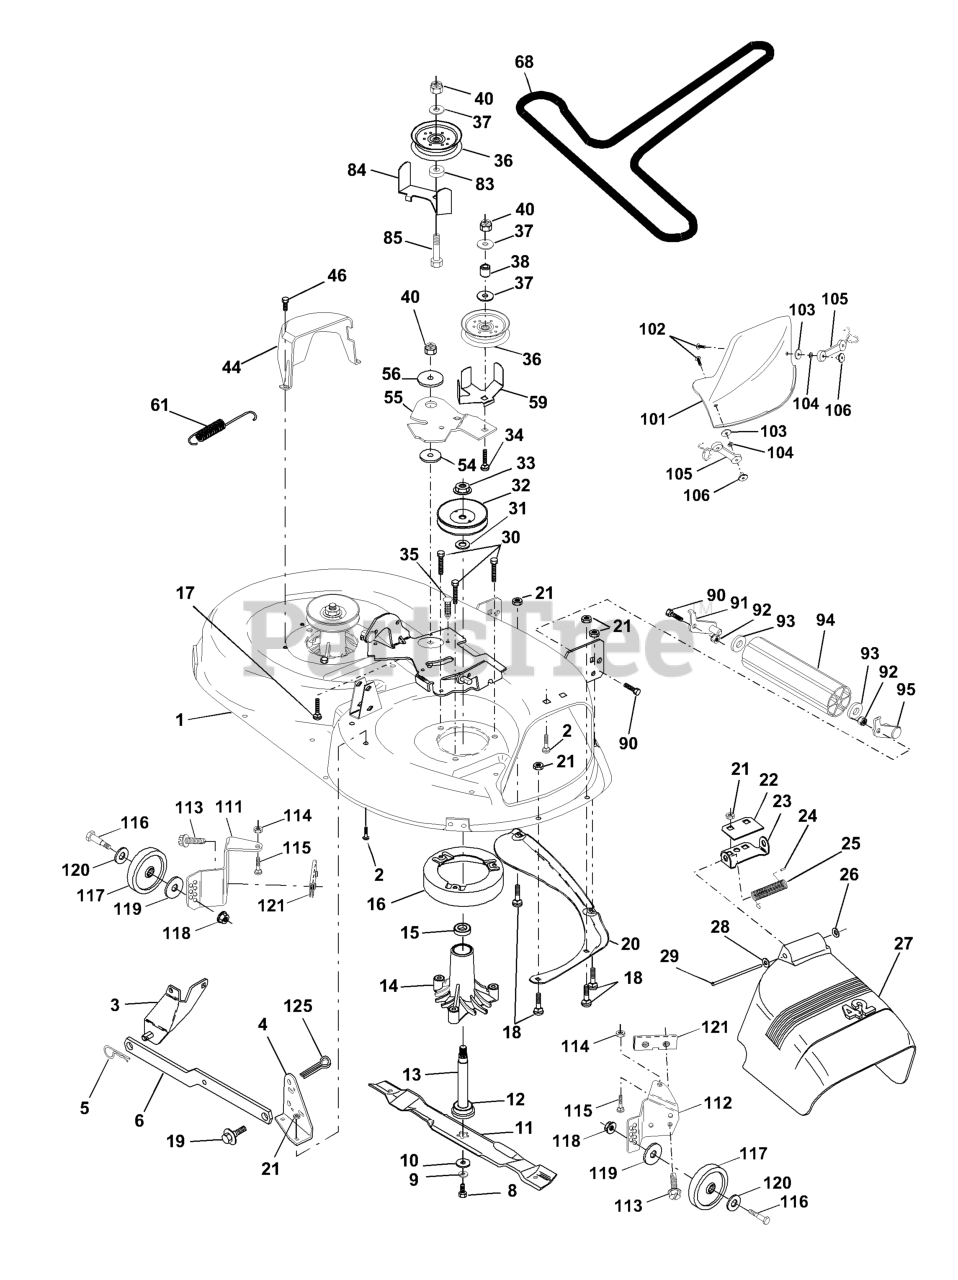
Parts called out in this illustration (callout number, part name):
1	DECK 42"
2	RP BOLT 5/16-18 X3/4 ZN/YEL GR
3	BRKT ASM SWAY BAR
4	BRKT DECK SW BAR
5	RETAINER-SPRNG RB
6	REAR SUSP ARM
8	BLADE BOLT
9	LOCKWASHER
10	WASHER.BLADE
11	BLADE.42".MULCH
12	BEARING.BALL.#6204.(MANDREL)
13	SHAFT ASM VENT
14	HOUSING.MANDREL.VENTED (MACHD)
16	STRIPPER
17	BOLT CARRIAGE
18	BOLT
19	BOLT SHD 5/16-18
20	BAFFLE
21	LOCKNUT
22	STIFFENER BRACKET
23	DEFLECTOR BRACKET
24	CAP-SLEEVE LT
25	SPRING TORSION
26	NUT PUSH M
27	SHIELD.DEFLECTOR.MOWER.42".BLK
28	Washer 11/32 X 5/8 X 16 Ga
29	ROD.HINGE
30	SCREW
31	WASHER
32	MANDREL PULLEY
33	NUT
35	FASTENER.XMAS.TREE
36	FLAT IDLER PULLEY
37	WASHER
38	IDLER SPRING SPACER
44	GUARD MANDREL LH BLACK
46	SCREW.1/4-20X5/8
54	HARDENED WASHER
55	IDLER ARM
56	SPACER RETAINER
59	GUARD, BELT
61	SPRING EXTENSION
68	V-BELT TRIPATH
84	KEEPER BELT
85	BOLT
90	BOLT
91	BRACKET LH (A)
92	NUT
93	Washer 17/32 X 7/8 X 16 Ga
94	NOSE ROLLER
95	BRACKET RH (B)
101	COVER MULCH 42"
102	SCREW
104	LOCKWASHER #10
105	LATCH ASSEMBLY
106	WELDNUT
111	BRACKET
112	BRACKET
113	SCREW.THDROL.5/16-18X3/4.TTY
114	NUT
115	BOLT.CARR.5/16-18X1/2
116	BOLT, SHOULDER
117	WHEEL.GAUGE.BLK.4.93
118	LOCKNUT
119	WASHER.5/16.FLAT.STE.STD.
120	Washer 17/32 x 15/16 x 12 Ga.
121	BRACKET.EXTRUDED.GAGE.WHEEL
125	Pin Cotter 1/4 x 1 Plated
